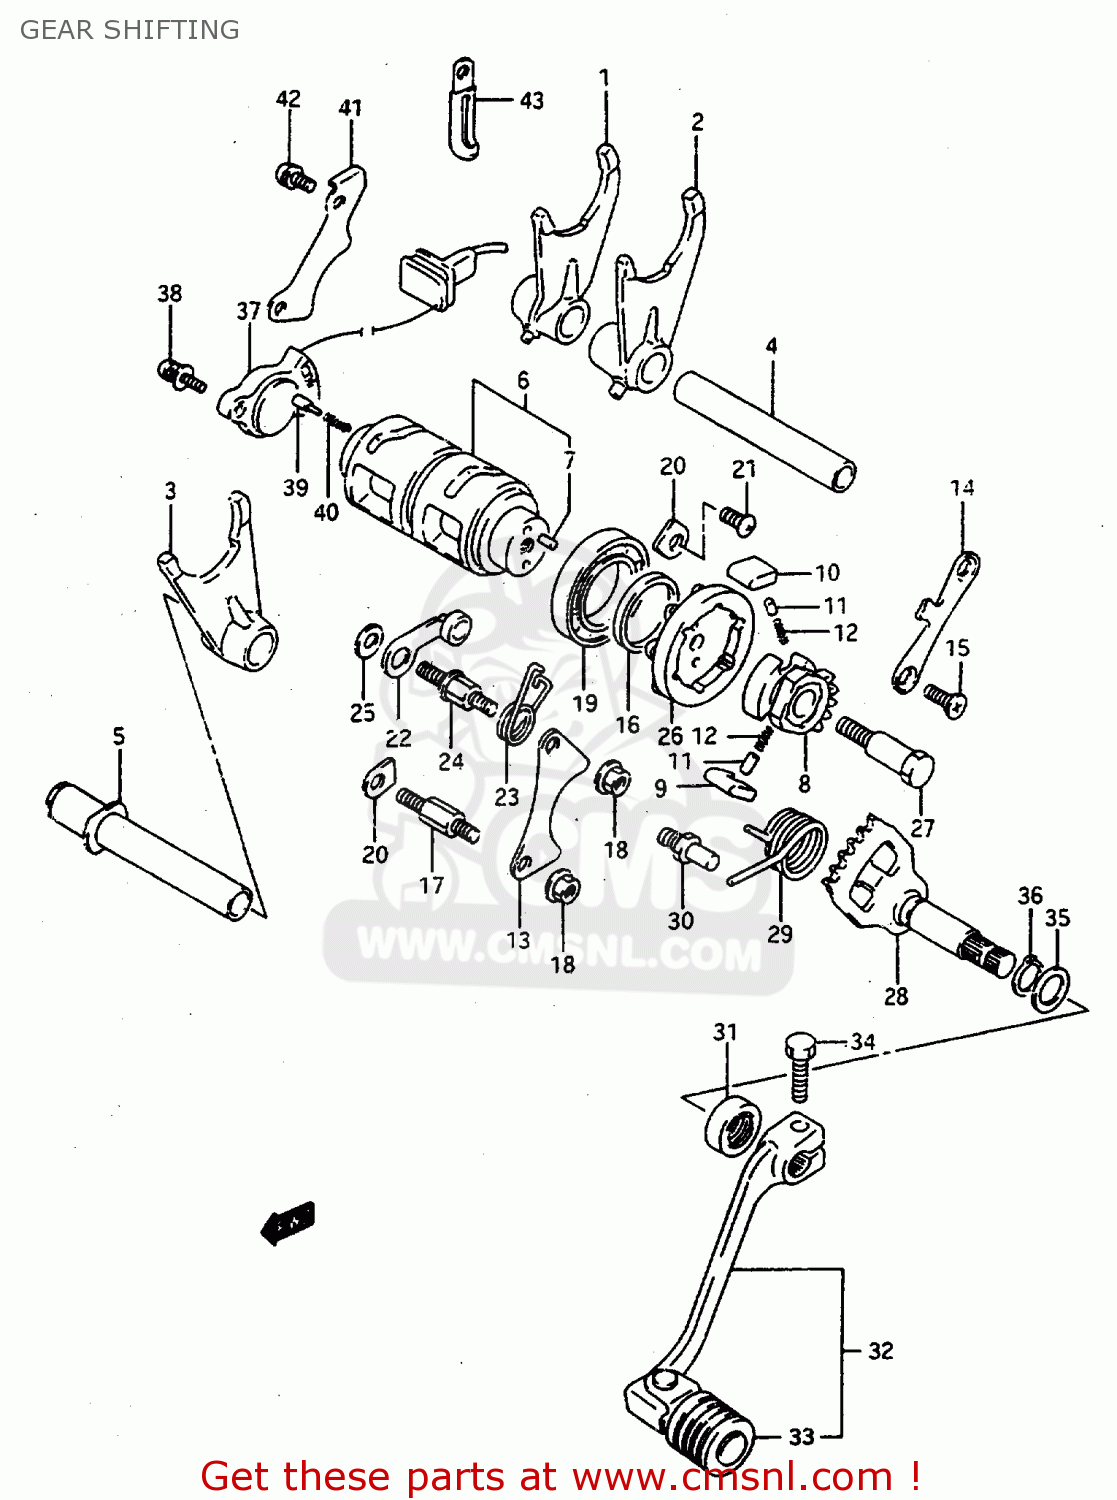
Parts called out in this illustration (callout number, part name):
1	FORK,GEAR SHIFT NO.1
2	FORK,GEAR SHIFT NO.2
3	FORK, GEAR SHIFTING NO.3
4	SHAFT,GEAR SHIFT FORK NO.1
5	SHAFT,GEAR SHIFT FORK NO.2
6	CAM,GEAR SHIFT
7	PIN
8	GEAR,GEARSHIFT CAM DRIVE
9	PAWL,GEAR SHIFT NO.1
10	PAWL,GEAR SHIFT NO.2
11	PIN(5X8)
12	SPRING
13	LIFTER,GEAR SHIFT POLE
14	GUIDE,GEAR SHIFT CAM
15	SCREW
16	WASHER(25X32X3)
17	BOSS,SHIFT PAWL LIFTER
18	NUT
19	BEARING(25X47X8)
20	RETAINER
21	SCREW
22	STOPPER,GEAR SHIFT CAM
23	SPRING
24	SUPPORT,CAM STOPPER ARM
25	WASHER
26	PLATE,GEAR SHIFT CAM
27	PIN,SHIFT CAM DRIVEN GEAR
28	SHAFT,GEAR SHIFT
29	SPRING
30	STOPPER,GEAR SHIFT ARM
31	OIL SEAL
32	LEVER ASSY,GEAR SHIFT
33	RUBBER,GEAR SHIFT PEDAL
34	BOLT
35	WASHER
36	CIRCLIP,12 MM
37	BASE ASSY,NEUTRAL SW TERMINAL
38	SCREW
39	PIN(5X15.5)
40	SPRING
41	CLAMP, LEAD WIRE
42	SCREW
43	CLAMP(L:45)
